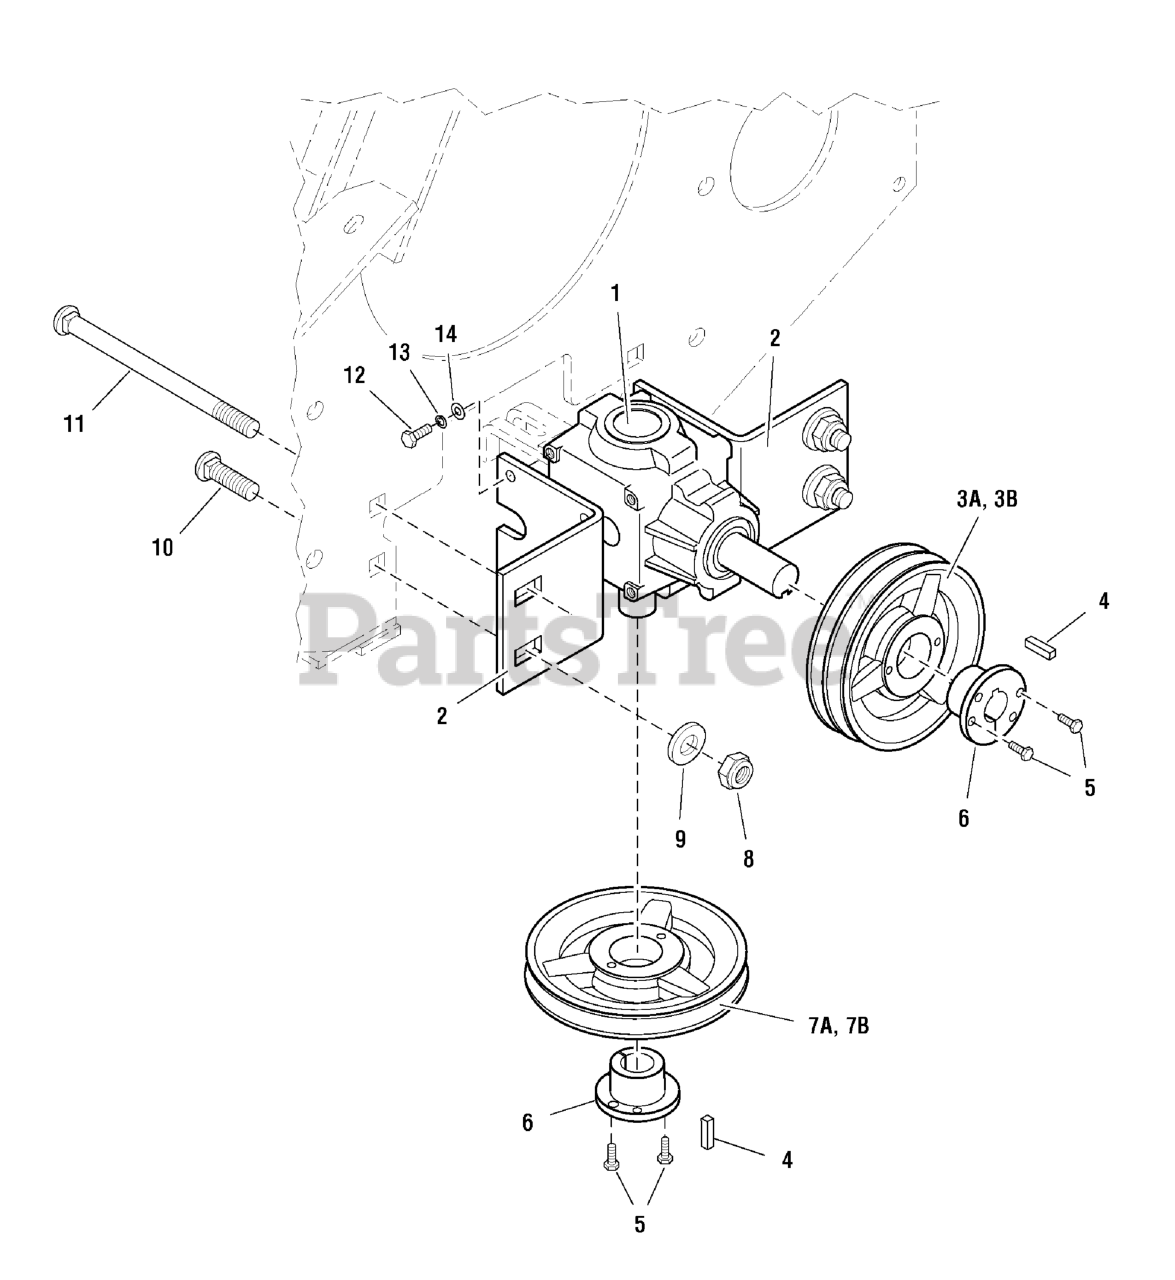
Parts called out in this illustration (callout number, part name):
1	GEARBOX
2	GEARBOX MOUNT BRACKET
3A	PULLEY, Gearbox Input
3B	PULLEY, Gearbox Input
4	KEY, 1/4 SQ. X 1
5	BOLT, 1/4-20 X 1" GD5 CZ
6	BUSHING, Tapered Hub
7A	PULLEY, Spindle
7B	PULLEY, Spindle
8	NUT, 1/2-13 Hex
9	WASHER, Frame Retaining
10	CARRIAGE BOLT, 1/2-13 x 2
11	CARRIAGE BOLT, 1/2-13 x 7
12	BOLT, 5/16-18 X 1 GD5 YZ
13	WASHER, 5/16 LOCK CZ
14	WASHER, 5/16" SAE
